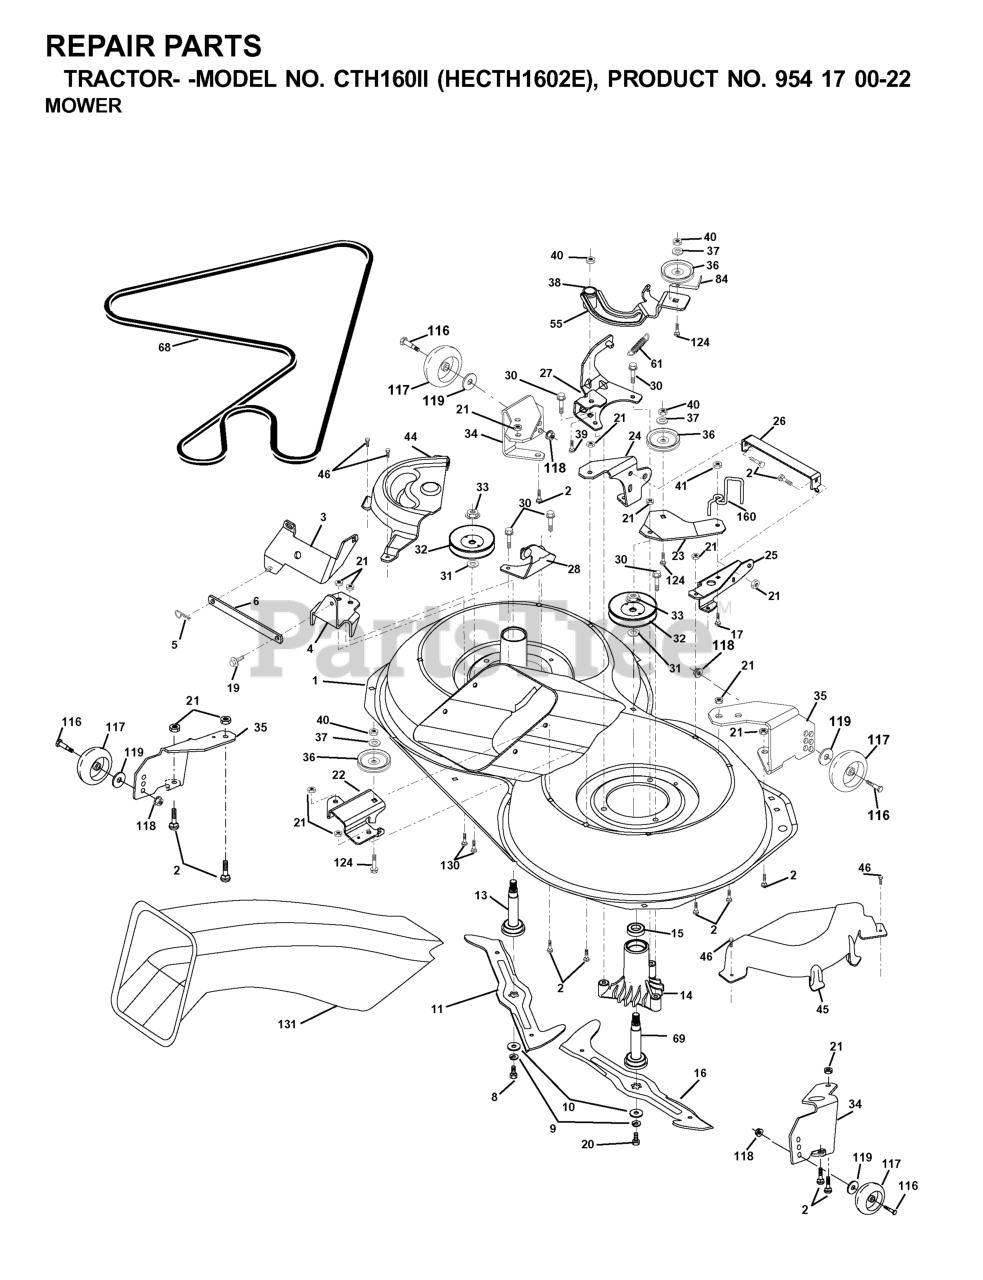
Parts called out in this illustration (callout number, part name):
1	Housing Asm. Mower 107 CRD
2	RP BOLT 5/16-18 X3/4 ZN/YEL GR
5	RETAINER-SPRNG RB
6	BAR.SWAY.92.CRD
8	BLADE BOLT
9	LOCKWASHER
10	WASHER.BLADE
11	BLADE, LH (CTH150)
13	SHAFT ASM VENT
14	HOUSING.MANDREL.VENTED (MACHD)
16	RP BLADE RH (CTH150)
17	BOLT.3/8-14X1.25
19	BOLT SHD 5/16-18
21	LOCKNUT
22	BRACKET.IDLER.RR.107.CRD
25	BRACKET.SUSPENSION.RF.107.CRD
26	BRACE.SUPT.SUSP.FRT.CRD
28	BRACKET
30	SCREW THDROL ROLLING WASHER HD
31	WASHER
33	NUT
36	PULLEY.IDLER.4.25
37	WASHER
41	NUT LOCK FLG 3/8-16 UNC
44	Cover Mandrel Lh 107 CRD
45	MANDREL COVER RH
46	SCREW.1/4-20X5/8
55	ARM.IDLER.107.CRD
68	HEX-BELT 107 MOWER
69	SHAFT.ASM.W/LWR.BRG.RH.THREAD
84	KEEPER, BELT IDLER
116	BOLT, SHOULDER
117	WHEEL GAGE DONUT
118	LOCKNUT
119	WASHER.5/16.FLAT.STE.STD.
124	BOLT.3/8-16X1.50
130	BOLT.CARR.SQNK.5/16-18UNC.X3/4
131	CHUTE BAGGER
